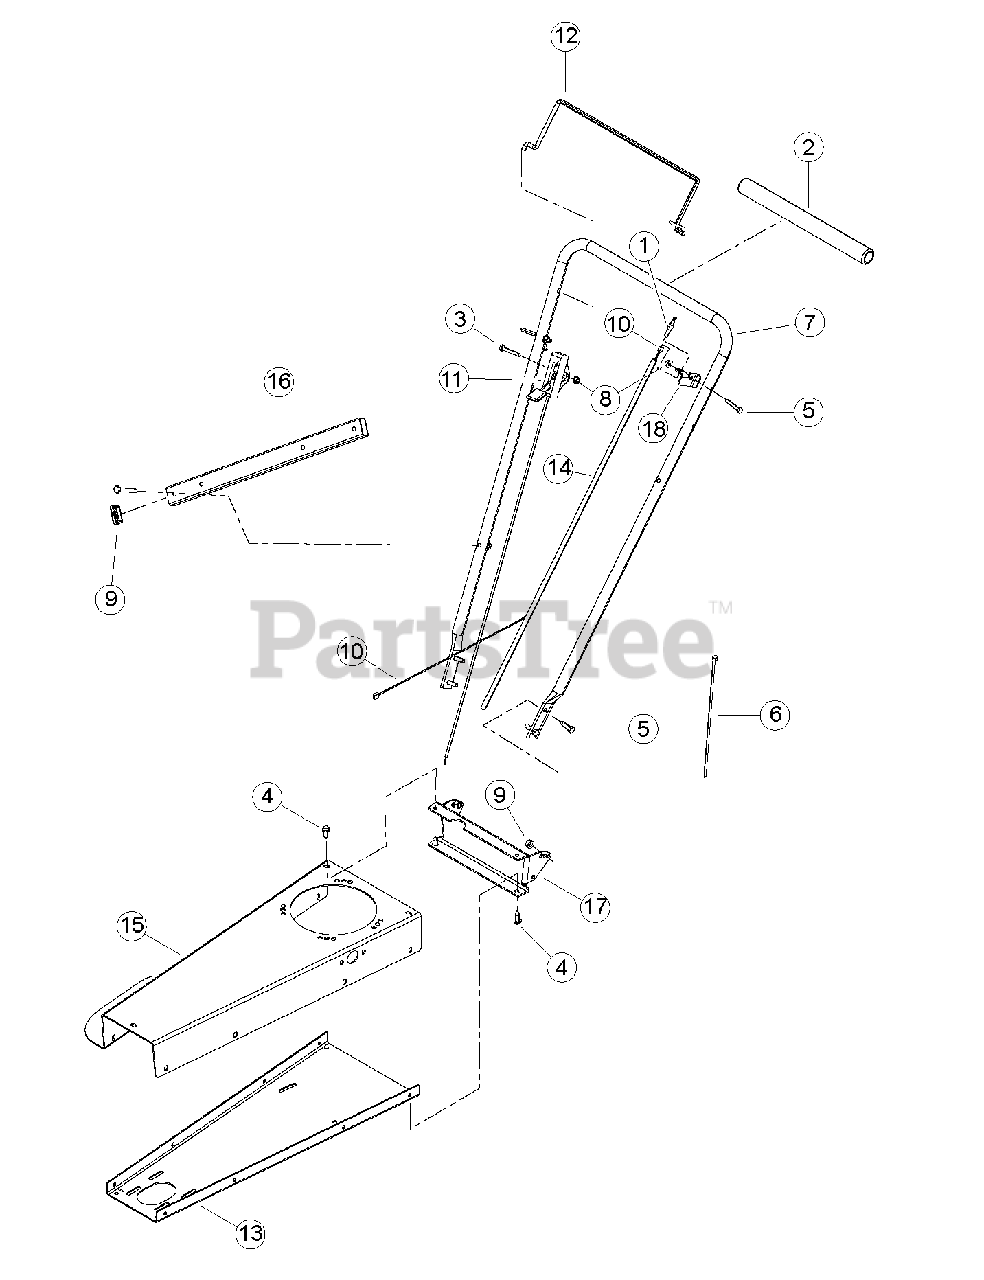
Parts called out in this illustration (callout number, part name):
1	SWITCH, ENGINE KILL
2	PAD, FOAM HANDLEBAR
3	BOLT, 1/4 X 1-3/4 HEX HD
4	SCREW,11/32 X 7/8 HWH AB THREAD ZP
5	BOLT, 1/4 X 1-1/2 HCS G5 ZP
6	STRAP, 11 IN. BLACK TIE
7	HANDLEBAR, TRIMMER
8	NUT, 1/4-20 NYLOCK - FLANGE
9	CAP, PLASTIC 3/4 X 1-1/2 TUBE
10	HARNESS, SUBARU KILL SWITCH
11	CONTROL, THROTTLE
12	WELDMENT, BAIL TRIMMER KILL
13	BOTTOM, TRIMMER FRAME
14	CONDUIT, 1/4 X 32 WIRE
15	BODY, TRIMMER
16	TUBE, CONTAINER HOLDER
17	CHANNEL, HANDLE SUPPORT
18	BRACKET, CABLE ANCHOR
